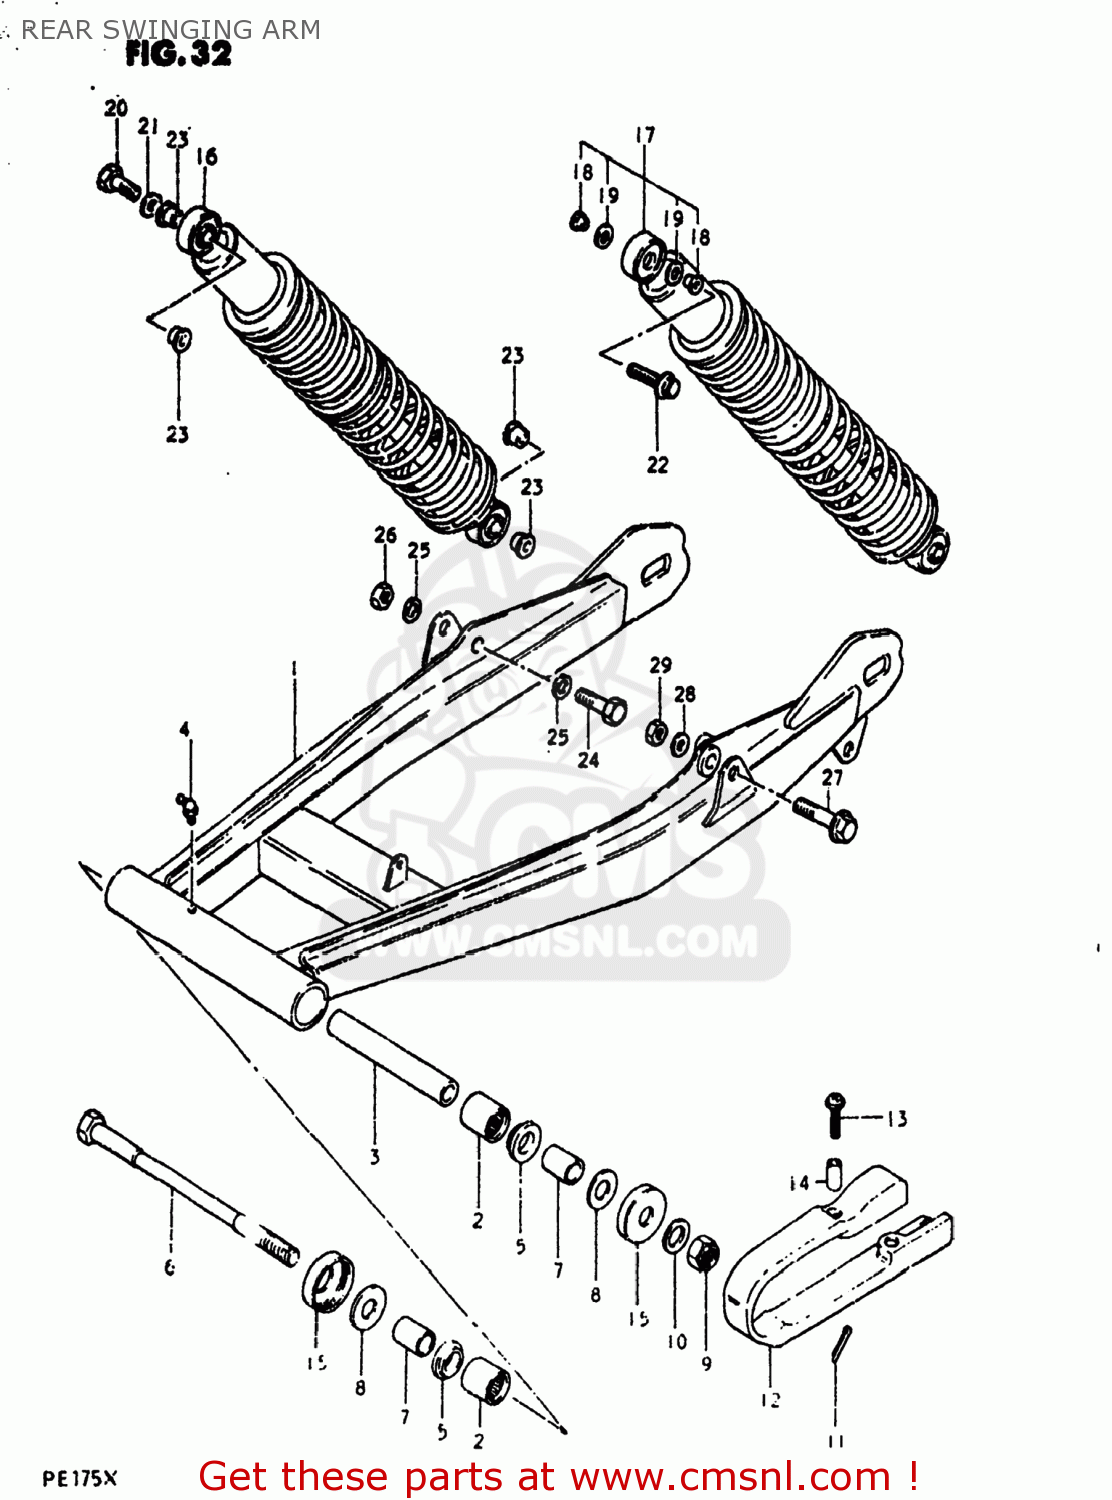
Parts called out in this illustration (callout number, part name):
1	SWING ARM ASSEMBLY,REAR
2	ROLLER BEARING (17X24X2
3	SPACER,SWING ARM,CENTER
4	NIPPLE,GREASE
5	BUSH,RR SWINGINGARM PIVOT
6	SHAFT,REAR SWING ARM
7	SPACER,RR SWGARM PIVOT
8	WASHER
9	NUT, REAR AXLE
10	WASHER
11	COTTER PIN
12	BUFFER,CHAIN TOUCH DEFLECTOR
13	SCREW,CHAIN TOUCH DEFEND
14	SPACER (5.5X8X4)
15	COVER,REAR SWING ARM DUST
16	ABSORBER ASSEMBLY,REAR SHOCK
17	ABSORBER ASSEMBLY,REAR SHOCK
18	SPACER,REAR SHOCK ABSORBER
19	DUST SEAL,REAR SHOCK
20	BOLT
21	WASHER
22	BOLT 10X40
23	SPACER,RR SHK ABS INNER
24	BOLT(8X46)
25	WASHER
26	NUT
27	BOLT(10X52)
28	WASHER
29	NUT
